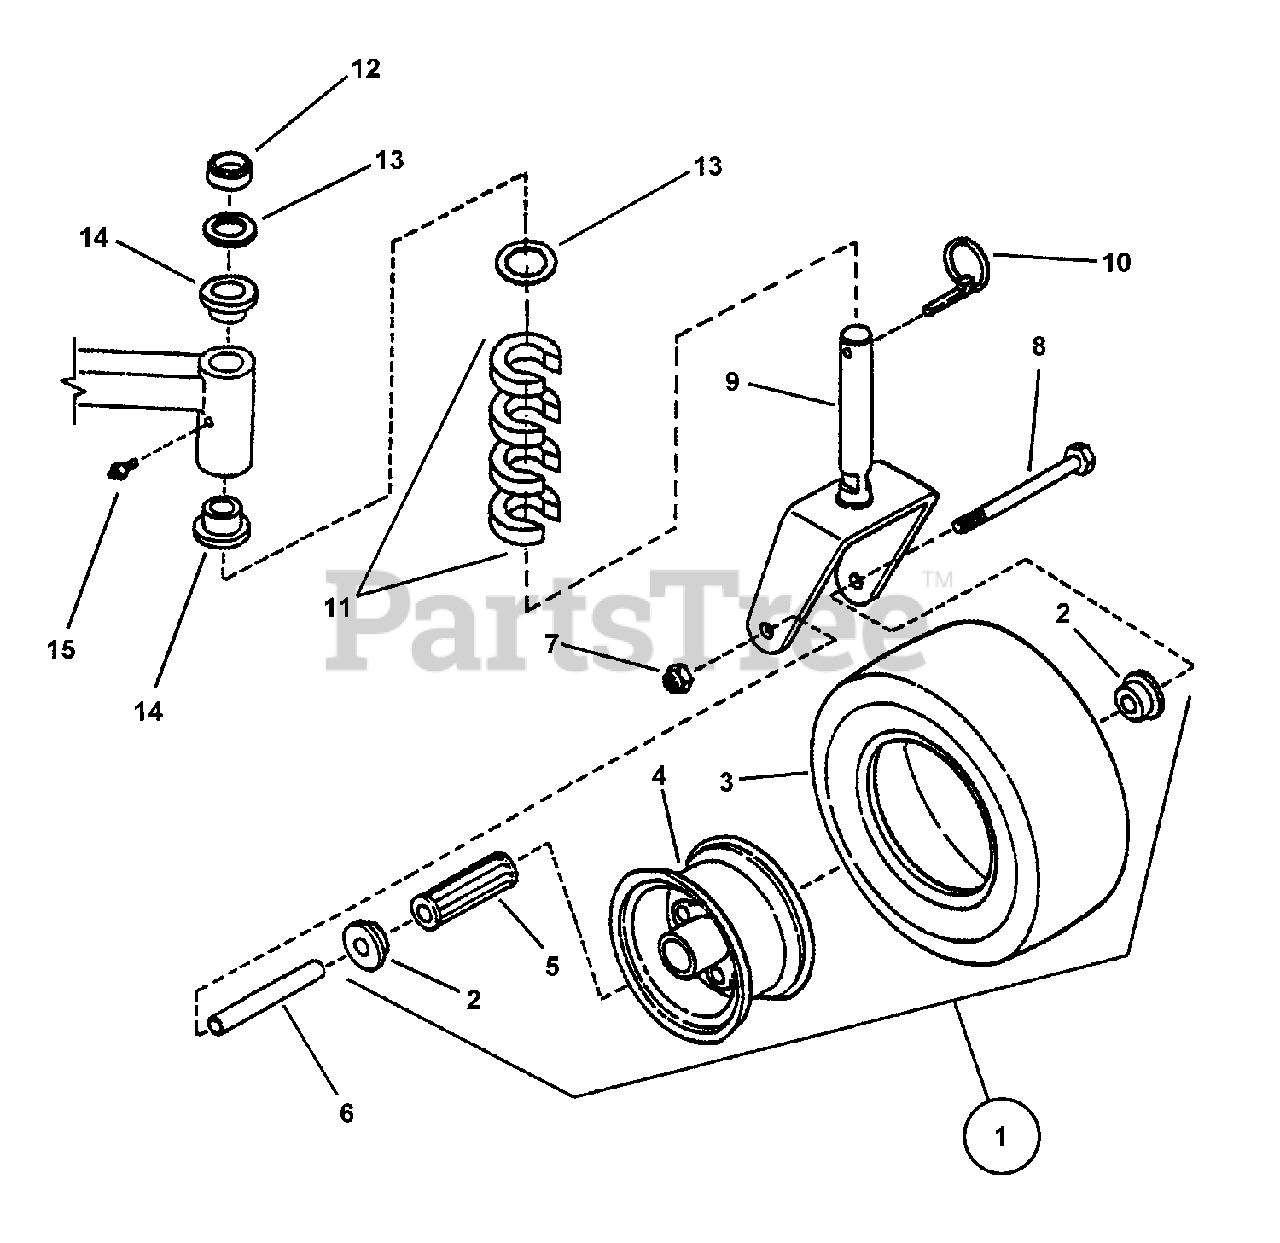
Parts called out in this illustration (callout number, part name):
1	* ASSEMBLY, Wheel & Tire (White Rim); incl. items 2 thru 5
1	* ASSEMBLY, Wheel & Tire (Gray Rim); incl. items 2 thru 5
2	RETAINER, Flanged
3	TIRE, 9 x 3.50-4
4	RIM, One-Piece Steel (White)
4	RIM, One-Piece Steel (Gray)
5	BEARING, Roller
6	SLEEVE, Axle
7	NUT, 1/2-13 HEX NYLON LOCK
8	BOLT, 1/2-13 X 5-1/2" GD5 YZ
9	WELDMENT, Yoke Caster
10	LYNCH PIN, 7/16" Heavy Duty
11	SPACER
12	SPACER, PM
13	BUSHING, 1"
14	BUSHING, Caster
15	LUBE FITTING, 1/4-28 Straight
